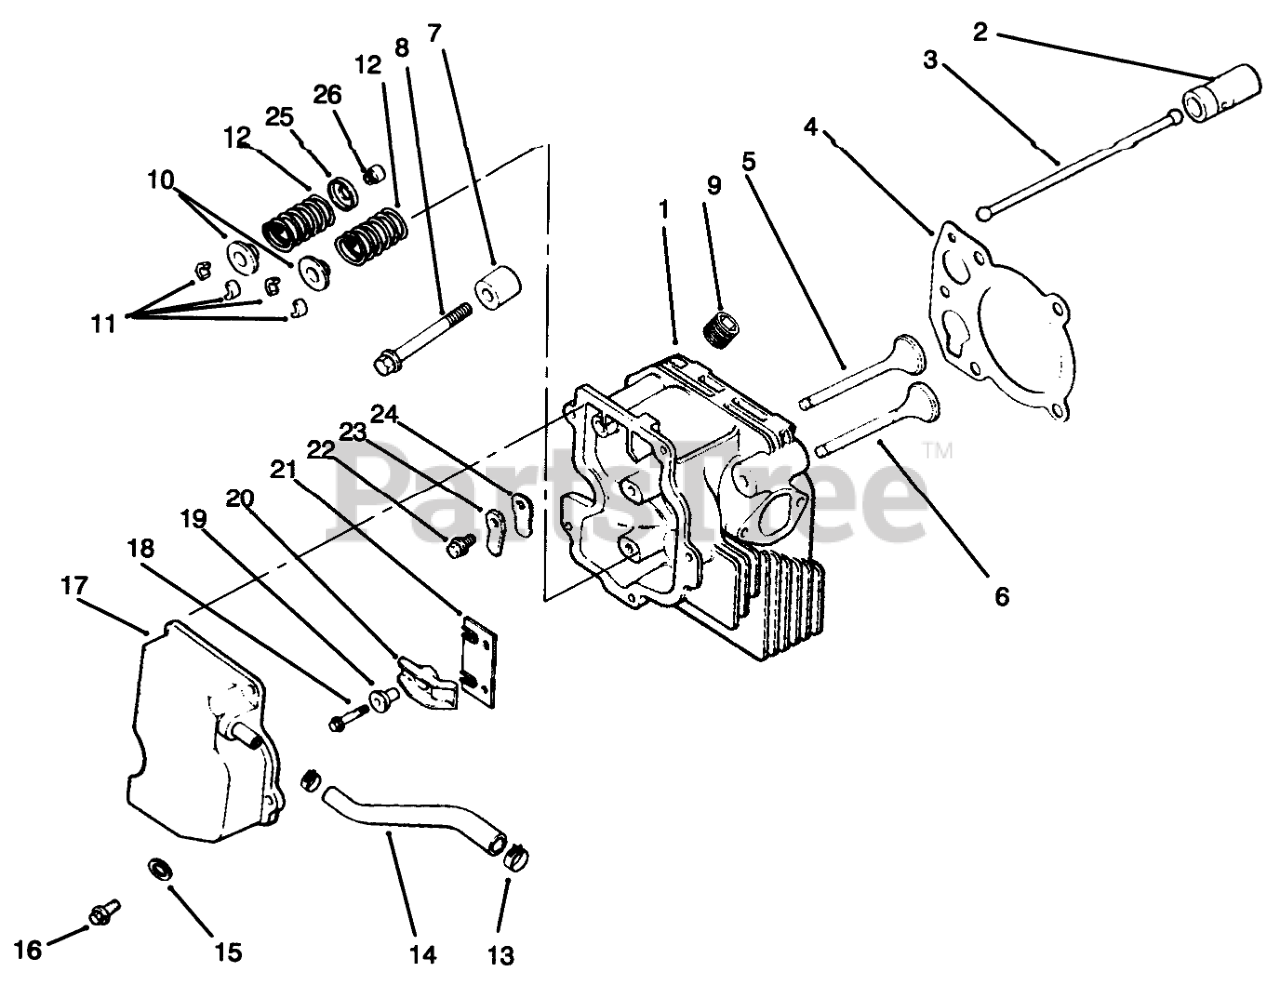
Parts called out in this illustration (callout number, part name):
1	Cylinder Head
2	Lifter-Valve
3	Rod-Push
4	Gasket-Cylinder Head
5	Valve-Intake STD
5	Valve-Intake .25
6	Valve-Exhaust STD
6	Valve-Exhaust .25
7	Spacer-Head Bolt
8	Screw M10x1.5x80
9	Plug
10	Cap-Spring, Valve
11	Retainer Kit
12	Spring-Valve
13	Clamp
14	Hose-Breather
15	Washer
16	Screw
17	Cover-Valve w/Nipple
19	Pivot-Rocker Arm
20	Arm-Rocker
21	Plate-Guide
22	Screw
23	Retainer-Reed
24	Reed-Breather
25	Retainer-Spring
26	Seal-Stem, Valve
